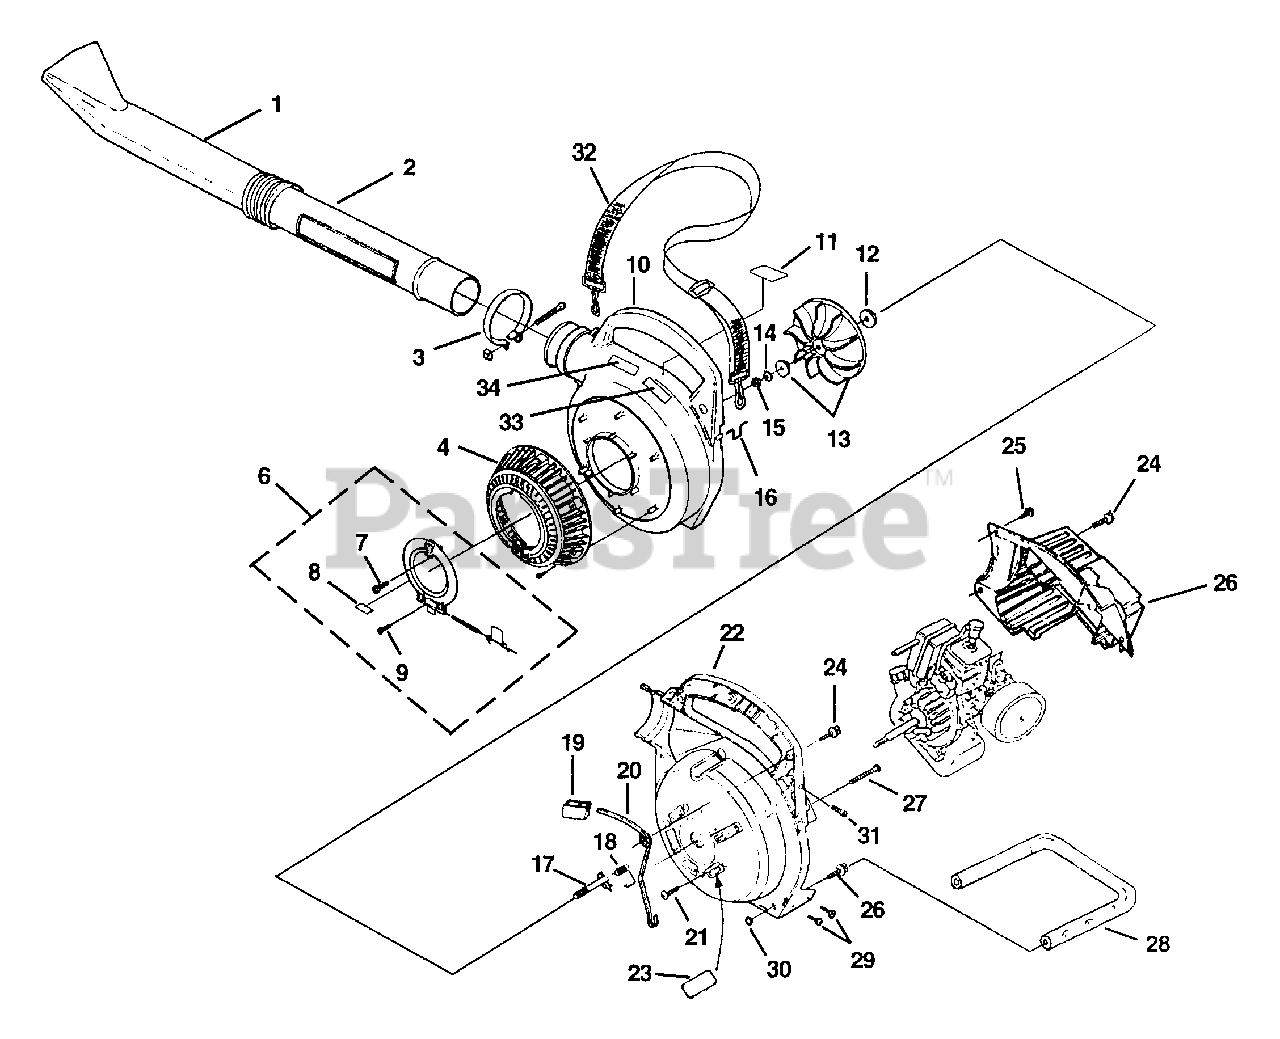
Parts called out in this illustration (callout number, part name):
1	TUBE KIT
3	CLAMP W/FASTENERS
4	GRILLE, BLOWER VAC
5	SCREW, #6 X 3/4" S.T.
6	COVER, ACCESS
7	SCREW, #10 X 5/8" S.T.
8	DECAL, SAFETY
9	SCREW #8 X 1/2" S.T.
10	HOUSING, VOLUTE
11	DECAL, WARNING
12	WASHER, FLAT
13	FAN KIT BLOWER
14	WASHER, BELLVILLE 3/8
15	NUT, HEX 3/8-24
16	LOOP WIRE
17	LATCH, THROTTLE
18	SPRING, THR. LATCH
19	TRIGGER, THROTTLE
20	LEVER, THROTTLE
21	SCREW, #10-24 X 3/4" S.T.
22	HOUSING, VOLUTE
23	KIT SEALING
24	SCREW, #10 X 3/4" S.T.
25	SCREW, #8 X 1/2" S.T.
26	SHROUD, COV.
27	SCREW, #10 X 1 5/8" S.T.
28	HANDLE, LOWER
29	SCREW, #8 X 1/2" S.T.P.H.
30	"O" RING
31	SCREW, #8-32 X 5/8" F.H.
32	STRAP, SHOULDER
33	DECAL, THROTTLE
34	DECAL, WARNING
